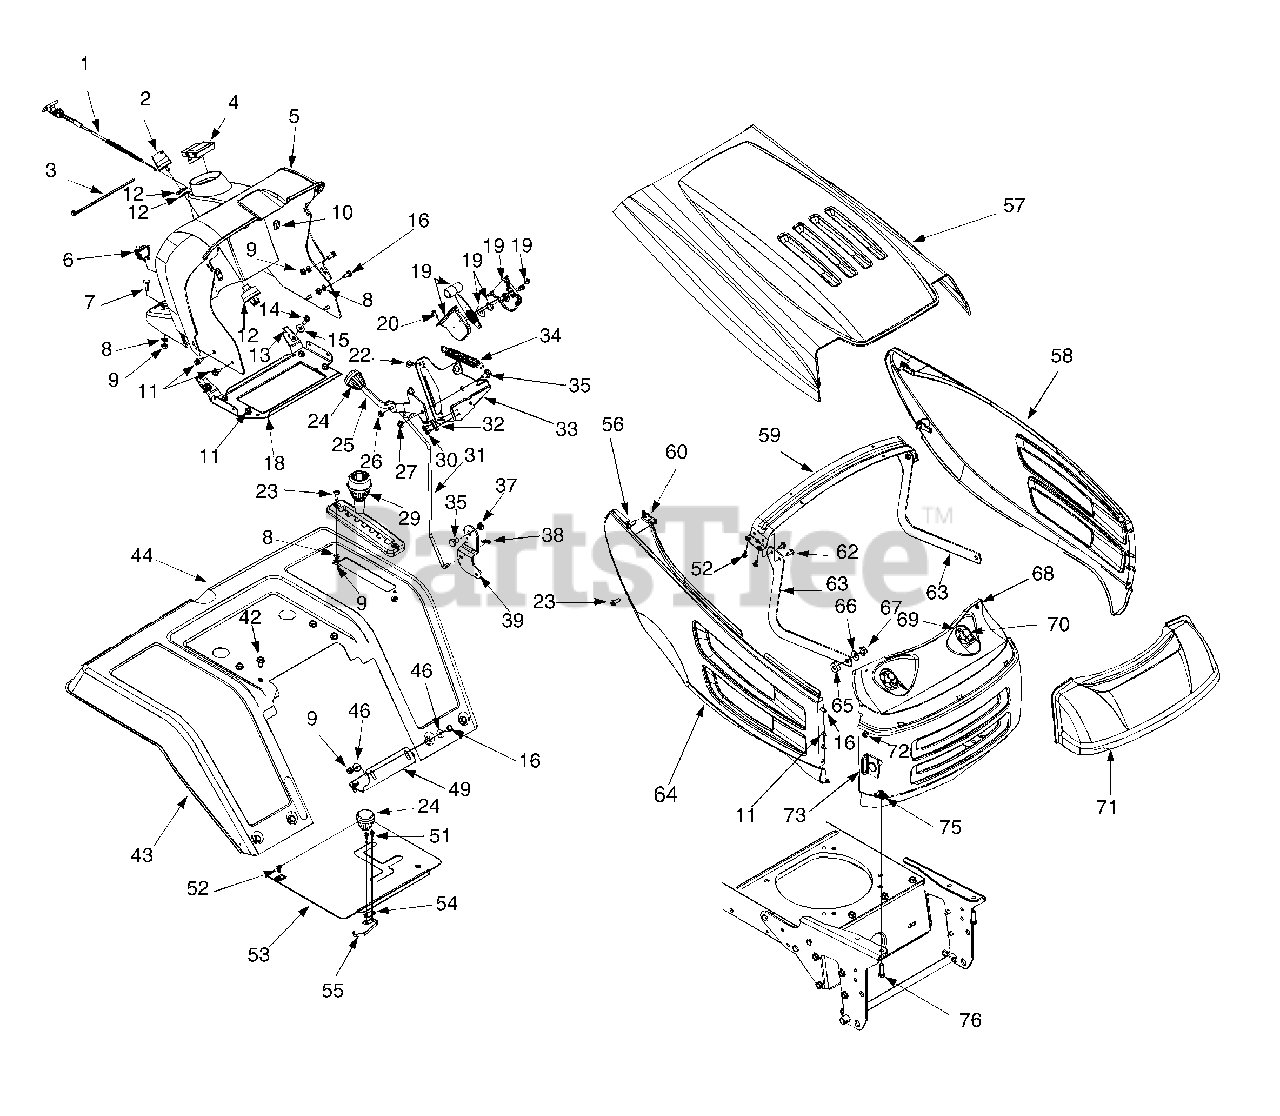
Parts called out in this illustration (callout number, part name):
1	Choke Cable
2	Ignition Key
3	Cable Tie
4	Ammeter
5	Dash Panel
6	Light Switch
7	Carriage Bolt 1/4-20 x 1" Lg.
8	L-Wash. 1/4" I.D.
9	Hex Nut 1/4-20 Thd.
10	Choke Retainer
11	Hex Wash. Hd. AB-Tapp Scr.
12	Ignition Switch
13	Speed Nut 1/4-20 Thd.
14	Hex Wash. Hd. TT-Tapp Scr.
15	Fl-Wash. 1/4" I.D.
16	Hex Bolt 1/4-20 x .62" Lg.
20	Truss Mach. AB-Tap Scr.
22	Truss Mach. AB-Tap Scr. .62" Lg.
23	Pan Hd. Mach. Scr. 1/4-20 x .75" Lg.
24	Knob
25	PTO Lever
26	Speed Cap Nut
27	Hex L-Nut 5/16-18 Thd.
30	Hex Wash. Hd. AB-Tap Scr.
31	Deck Connection Rod
32	Switch Plate
35	Shld. Bolt 1.62" Lg.
37	Hex L-Nut 5/16-18 Thd.
38	Hairpin Clip
39	Control Deck Pivot Bracket
42	Hex Wash. Hd. AB-Tapp Scr.
46	Bell-Wash. 1/4" I.D.
52	Truss Hd. B-Tapp Scr.
55	Spring Switch
56	Rubber Bumper
62	Hex Wash. Hd. TT-Tap Scr.
66	Spr. Washer
67	Flange L-Nut 3/8-16 Thd.
68	Retainer Nut
69	Socket
70	Lamp
71	Lens
72	Hex Sems Nut 1/4-20 Thd.
76	Hex Bolt 5/16-18 x 1" Lg.
